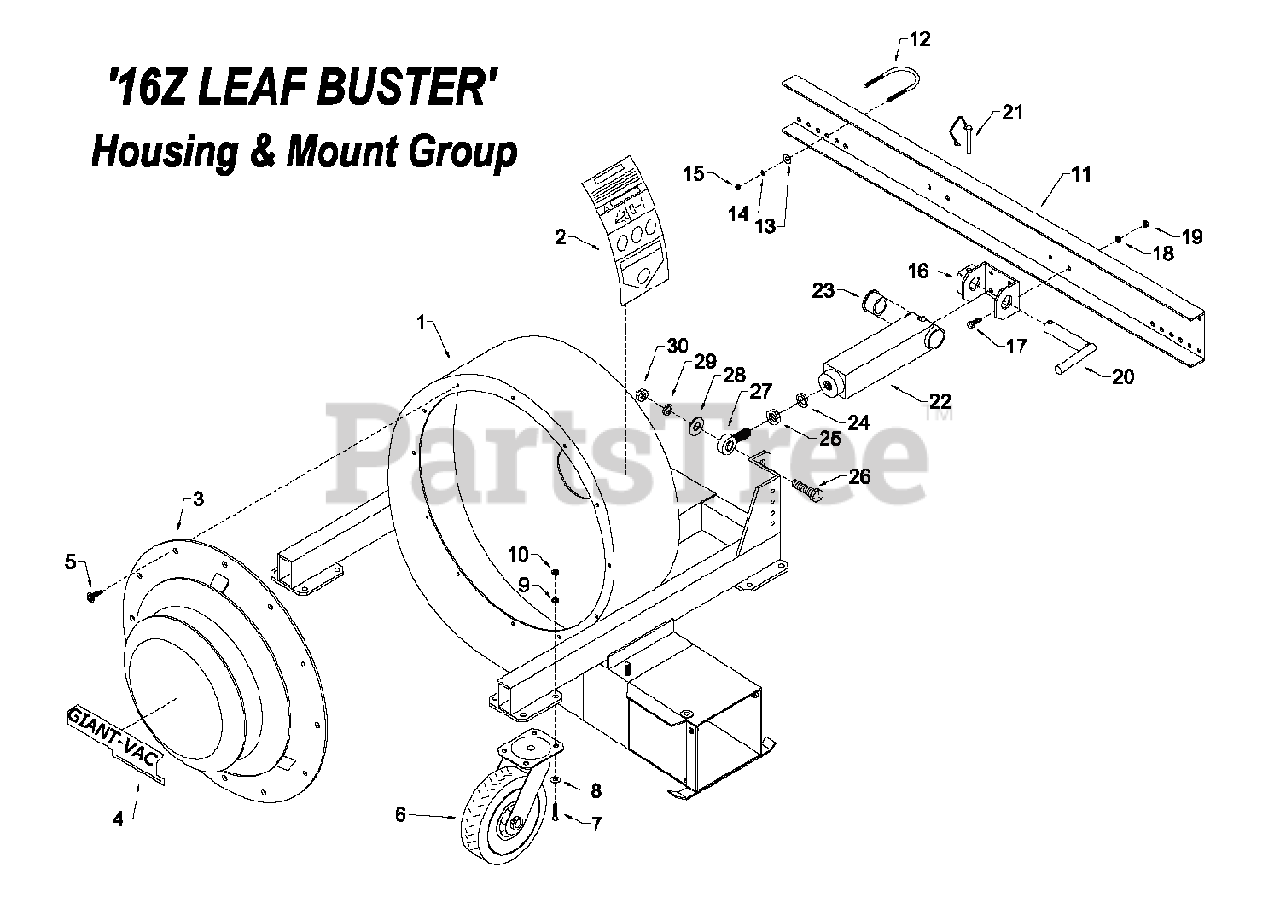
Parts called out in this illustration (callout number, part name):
1	Base, housing & frame
2	Decal - Caution/Danger combo
3	Baffle, intake
4	Decal - 'Giant-Vac' - 9" White-on-black
5	Bolt, 'F' thread - 5/16-18 x 3/4"
6	Assy, caster wheel & tire
7	Bolt, hex head - 3/8-18 x 1"
8	Washer, flat - 3/8"
9	Washer, split lock - 3/8"
10	Nut, hex finish - 3/8-16
11	Bumper, adjustable 2 pt hitch
12	Bolt, 'U' - 3/8" x 2-1/4" dia
13	Washer, flat - 3/8"
14	Washer, split lock - 3/8"
15	Nut, hex finish - 3/8-16
16	Bracket, 2 pt hitch
17	Bolt, hex head - 3/8-16 x 3/4"
18	Washer, split lock - 3/8"
19	Nut, hex finish - 3/8-16
20	Pin, hitch - 1" dia x 5"
21	Pin, snapper - 1/4" x 2"
22	Strut, 2 pt hitch
23	Bushing, flange - 1" id
24	Washer, split lock - 3/4"
25	Nut, hex jam - 3/4-16
26	Bolt, hex head - 3/4-10 x 2-1/4" gr5
27	Linkage, spherical rod end - 3/4 x 3/4-16 UNF
28	Washer, flat - 3/4"
29	Washer, split lock - 3/4"
30	Nut, hex finish - 3/4-10
